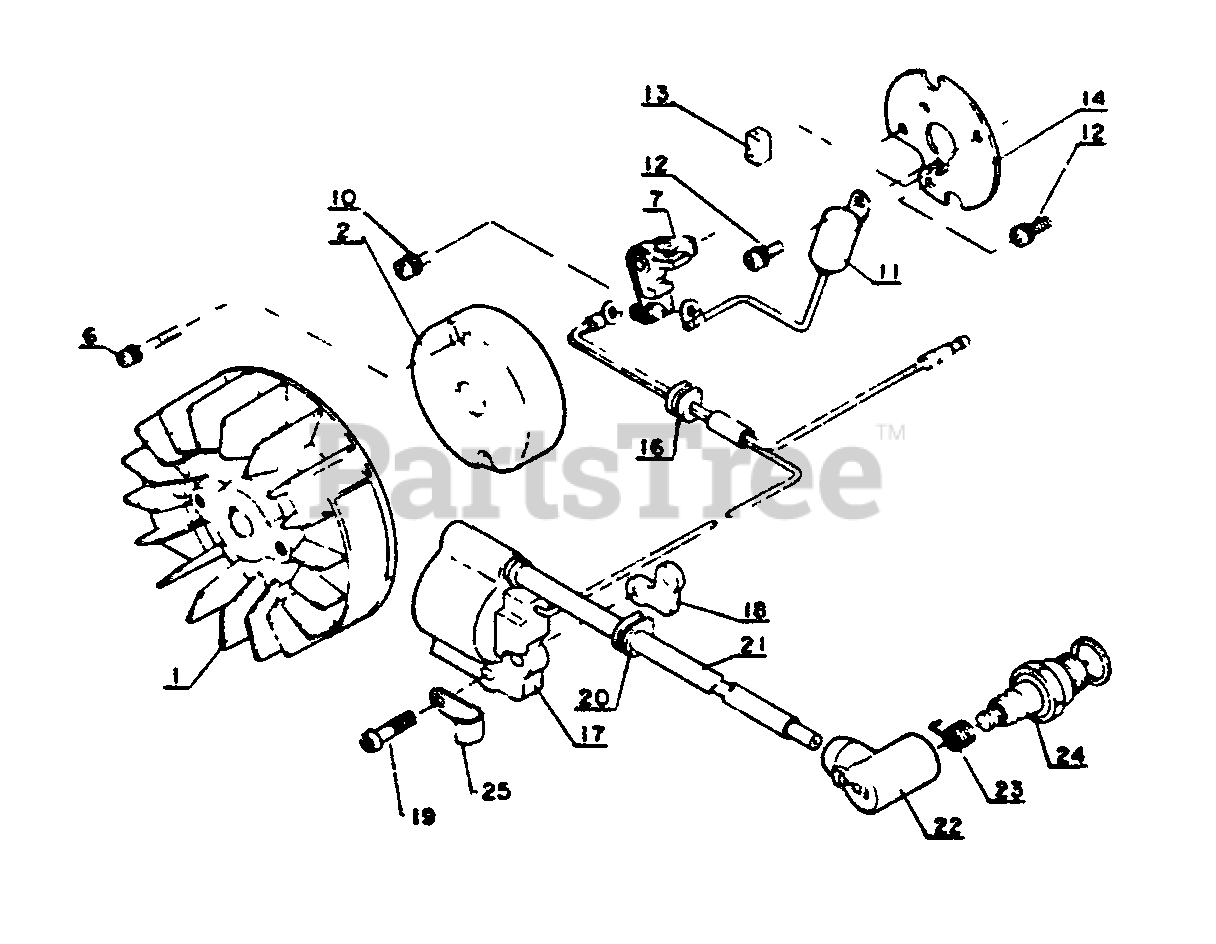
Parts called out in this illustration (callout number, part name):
1	FLYWHEEL
2	COVER, BREAKER
6	SCREW - 3X22
7	CONTACT POINT SET
10	SCREW - 4X8
11	CONDENSER
12	SCREW - 4X12
13	PAD
14	PLATE, STATOR
17	COIL, IGNITION
19	SCREW - 4X20
20	BUSHING
22	CAP, SPARK PLUG
23	TERMINAL, SPARK PLUG CAP
24	SPARK PLUG -- BM-6A
25	CLIP
